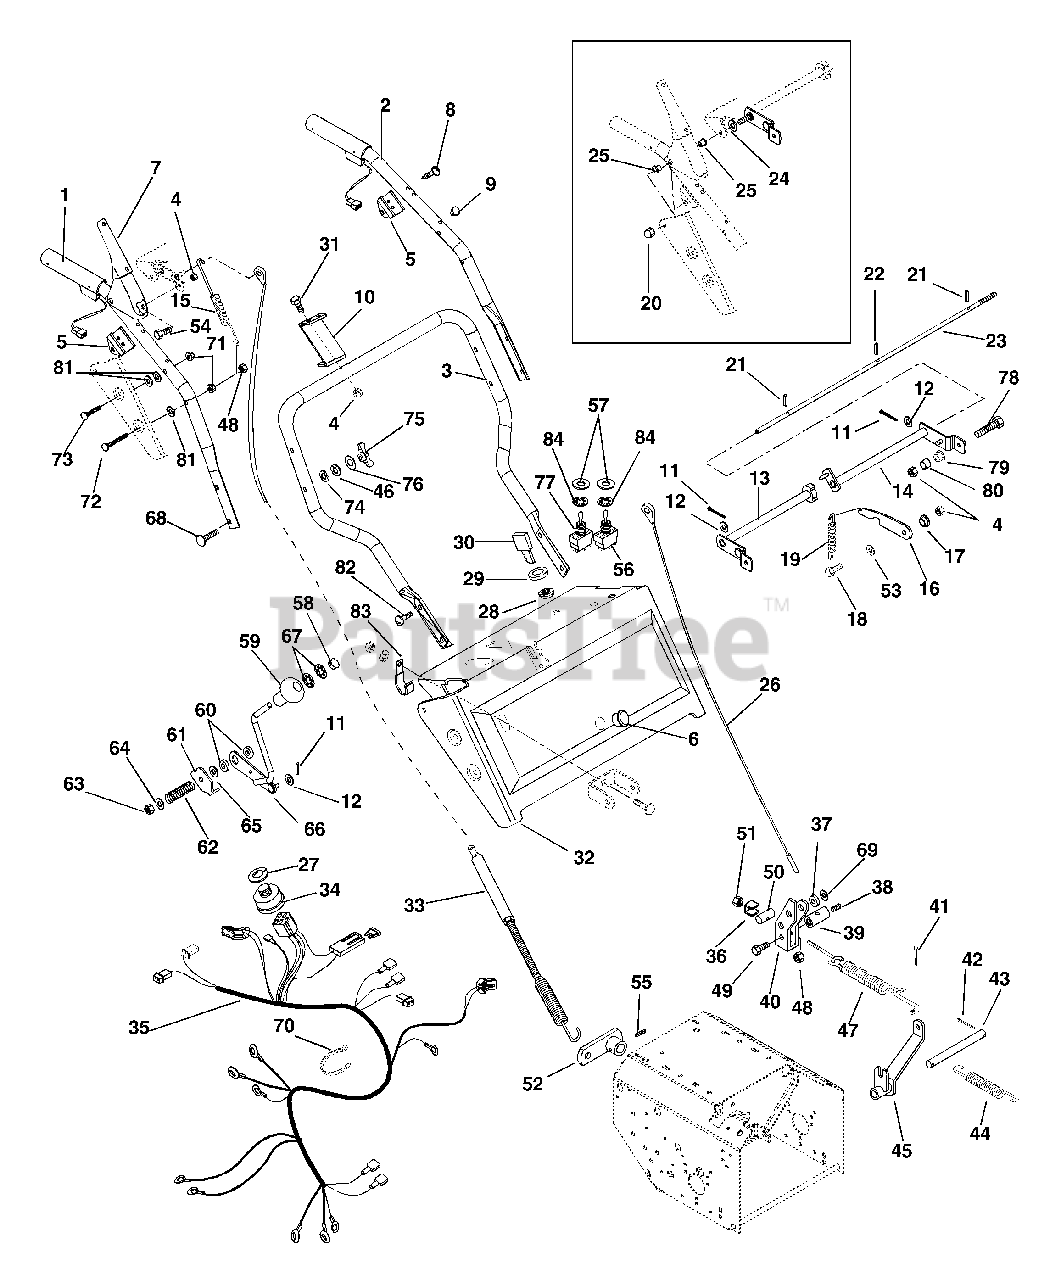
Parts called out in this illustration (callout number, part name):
1	HANDLEBAR, UPPER RH
2	HANDLEBAR, UPPER LH
3	HANDLEBAR, LOWER
4	@NUT-LK-CTR .25-20 YWZC
5	HANDLE PIVOT
6	SNAP BUSHING
7	CLUTCH LEVER - COATED
8	SCR-TAP 12-24X1.50 CROVH YZ BT
10	BRACKET, CABLE SUPPORT
11	@PIN-CTR .09X.50 EXTPRSQCT YWZ
12	@WSHR-FL-STL.281X.62X.065 YWZC
13	LEVER,RH
14	LEVER, L.H.
15	SG-TENS .051X.50X4.87
16	ARM, LATCH
17	BSHG-FLG .265X.437X.329X1.00
18	@BLT-HEX .25-20X.75 GR5 YWZC
19	SG-TENS .048X.44X1.75 WLD 9
20	NUT-CROWN .312-18 YWZC
21	PIN-ROLL .156X.75
22	PIN-ROLL .125X1.00
24	WSHR-FL-STL .323X.625X.062 YWZ
25	BSHG-FLG .325X.465X.333X.685
26	CABLE, TRACTION CLUTCH
27	WSHR-LK-INT .625X.045 YWZC
28	NUT-PANEL .625-32 GRECO
29	CAP - IGNITION SWITCH
30	KEY -W/CAP
31	@BLT-HEX .25-20X1.50 GR5 YWZC
32	PANEL W/DECAL - SB936
33	CABLE, BLOWER CLUTCH
34	SWITCH ASSEMBLY
35	WIRE HARNESS-HOT GRIPS & LIGHT
36	ADAPTER SPACER
37	SPACER 1.00 X .64 X .38
38	SCR-SET .31-18X.38 SKHCUPDL
39	ROD ADAPTER
40	CLUTCH ENGAGEMENT YOKE
41	@PIN-CTR .09X.50 EXTPRSQCT YWZ
42	@PIN-CTR .09X1.00 EXTPRSQCT YZ
43	ROD, FORK PIVOT
44	SG-TENS .080X.73X3.06 WLD 20
45	FORK, CLUTCH
46	WSHR-LK .312X.097 HVY YWZC
47	SPRING ASSEMBLY
48	@NUT-LK-CTR .31-18 YWZC
49	@BLT-HEX .31-18X.75 GR5 YWZC
50	ADAPTER
51	@NUT-LK-NYL .312-18 YWZC
52	LEVER, CLUTCH
53	WSHR-FL-STL .281X1.000X.063
54	@BLT-HEX .25-20X.50 GR5 YWZC
55	PIN-ROLL .156X.88
56	SWITCH, ON/OFF
57	WSHR-FL-STL .505X.875X.024 PL
58	HOLE PLUG
59	KNOB
60	FRICTION WASHER
61	PRESSURE FLANGE
62	SG-COMP .187X.56X1.62
63	@NUT-LK-CTR .38-16 YWZC
64	@WSHR-FL-STL.406X.812X.065 YWZ
65	SPACER .406X.620X.125
66	LEVER, DEFLECTOR
67	RG-RTNG-EXT .375X.010
68	@BLT-RDHDSQNK .31-18X2.25 G5YZ
69	WSHR-FL-STL .630X1.005X.062 YZ
70	CABLE TIE LG 5-1/2
71	@NUT-SPNLK-FLG .312-18 YWZC
72	BLT-RDHDSQSHNK.31-18X2.75G2YWZ
73	@BLT-RDHDSQNK .31-18X1.75 G5YZ
74	WASHER,SADDLE-.320 X.937 X.062
75	KNOB - WING .312-18 UNC
76	WSHR-FL-STL .328X.875X.062YWZC
77	SWITCH, CHUTE ROTATION
78	@BLT-HEX .25-20X1.00 GR5 YWZC
79	@NUT-SPNLK-FLG .25-20 YWZC
80	SPACER .265 X .355 X .312
81	WSHR-FL-STL .505X.880X.072 YWZ
82	BLT-SERHFWH .38-16X.75 YWZC
83	J-CLAMP
84	WSHR-LK-INT .563X.040 YWZC
